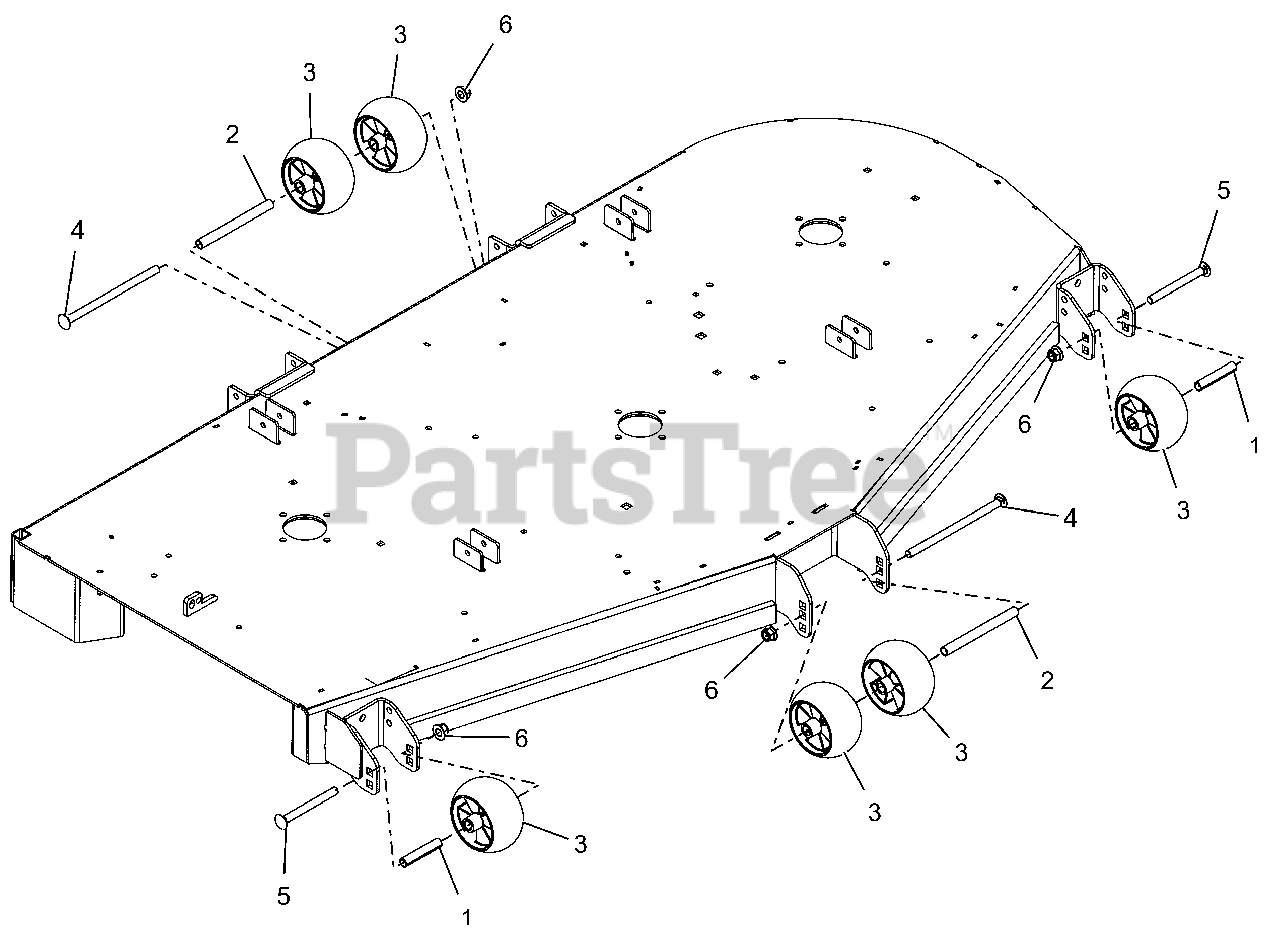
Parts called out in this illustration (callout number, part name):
1	SPACER, .510X.625X3.35
2	SPACER, .510X.625X6.50
3	ANTI-SCALP WHEEL - 5X3 CTR
4	@BLT-RDHDSQNK .50-13X8.50 G5YZ
5	BLT-RDHDSQNK .50-13X5.00 GR5YZ
6	@NUT-LK-NYL-FLG .50-13 YWZC
